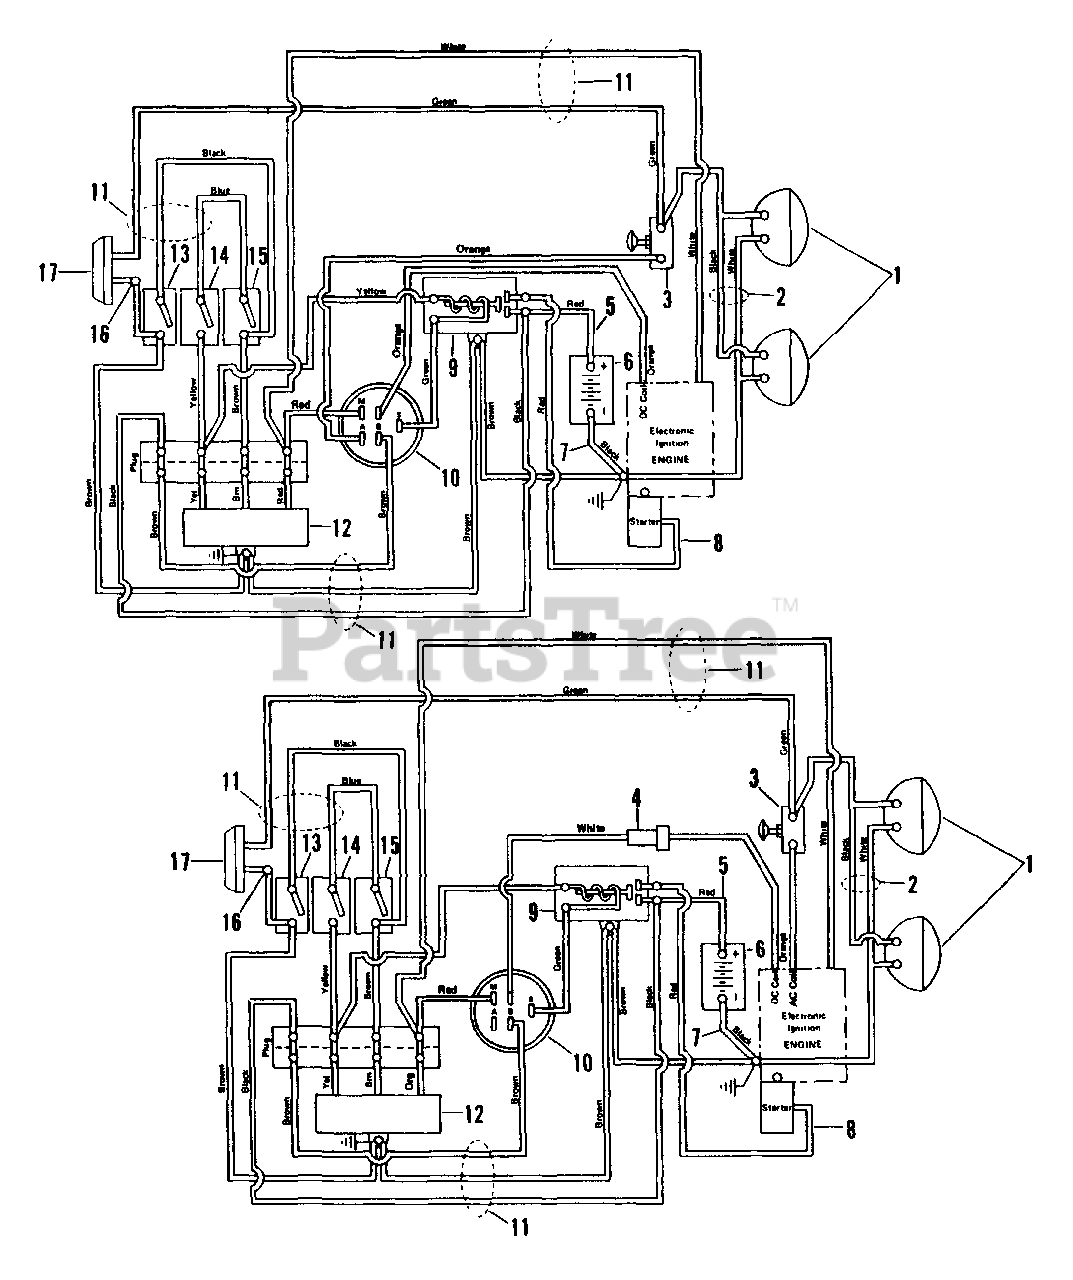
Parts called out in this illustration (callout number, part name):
1	HEAD LIGHT
2	WIRE HARNESS - HEADLIGHT
3	LIGHT SWITCH
4	15 AMP FUSE
5	STARTER CABLE
6	BATTERY
7	GROUND CABLE
8	STARTER CABLE 16"
9	SOLENOID
10	IGNITION SWITCH ASSEMBLY
11	WIRE HARNESS
11	WIRE HANRESS 10HP (BAL)
12	MODULE
13	SWITCH SEAT
14	SWITCH INTERLOCK
16	MALE DISCONNECT ADAPTER
17	TAIL LIGHT ASSEMBLY W/BULLET
